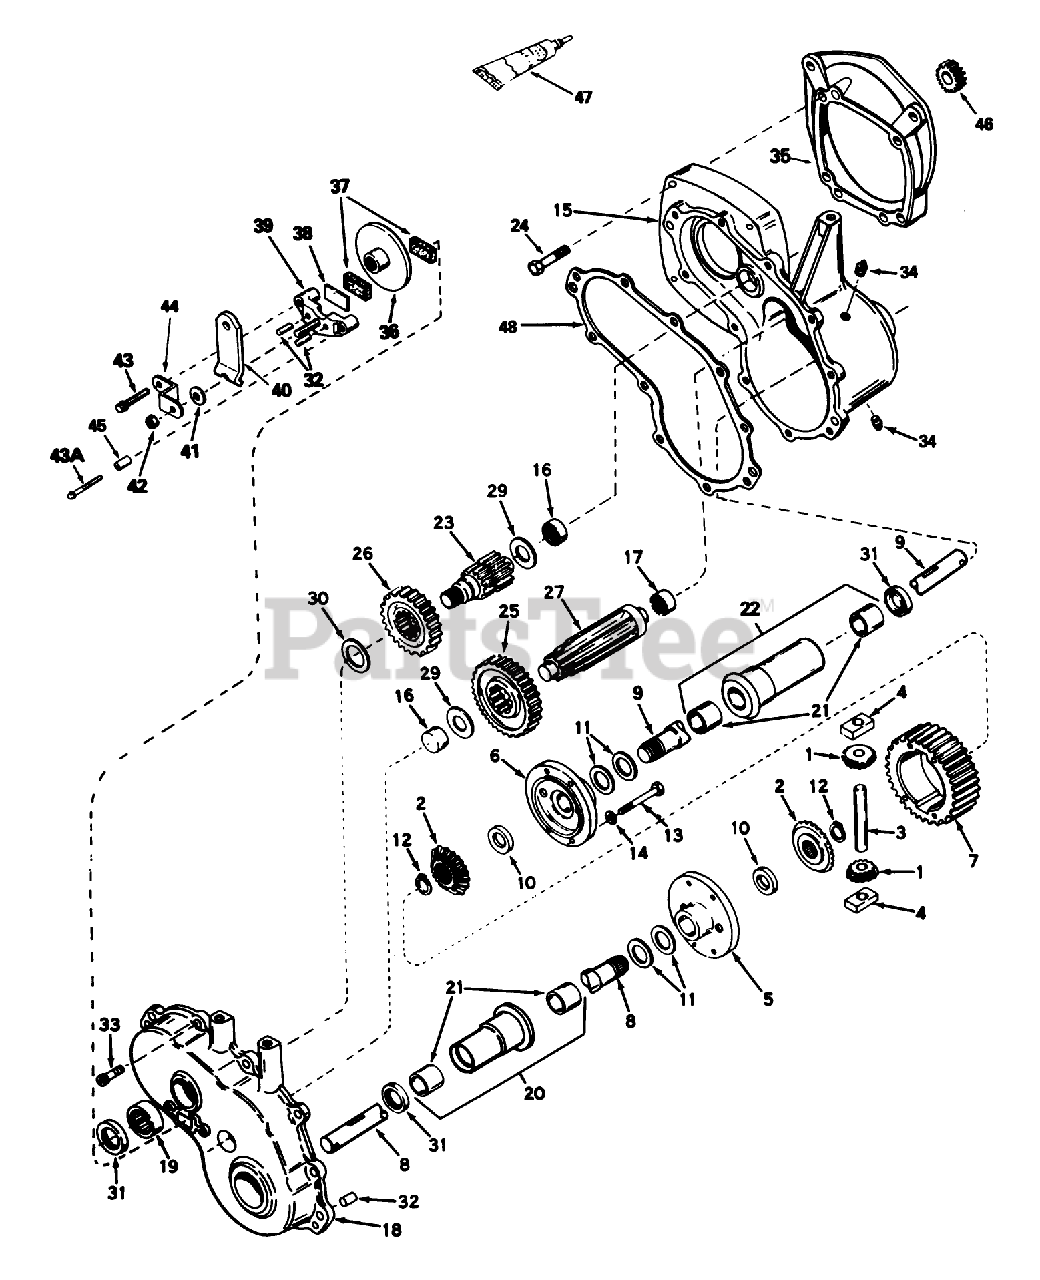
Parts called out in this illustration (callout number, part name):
1	Pinion-Bevel
2	Gear-Bevel
3	Pin-Drive
4	Biock-Drive
5	Carrier-Differential
6	Carrier-Differential
7	Gear-Ring
8	Axle 16-5/8"
9	Axle-21-57/64"
10	Washer
11	Washer
12	Ring-Snap
13	Screw-Hex Hd.
14	Lockwasher
15	Case Assembly (Incl. Ref. #16 17)
16	Bearing
17	Bearing-Needle
18	Cover Assembly (Incl. Ref. #16 19)
19	Bearing Needle
20	Housing Bushing Assembly (6-5/8" long) (Incl. Ref. #21)
21	Bushing
22	Housing Bushing Assembly (8-5/8" long) (Incl. Ref. #21)
23	Shaft-Brake
24	Screw-Hex Hd.
25	Gear-Output
26	Gear-Spur
27	Shaft-Output
29	Washer
30	Washer
31	Seal-Oil
32	Dowel Pin
33	Screw-Thread Forming
35	Plate-Adapter
36	Disc-Brake
37	Brake Pad
38	Brake Pad Plate
39	Nozzle-Carburetor
40	Lever-Brake
41	Washer
42	Locknut
43	Ring Set (.020 O S)
43A	Screw-Hex. Flange
44	Bracket
45	Spacer
46	Gear-Spur 22T
47	Gasket Eliminator
48	Gasket
